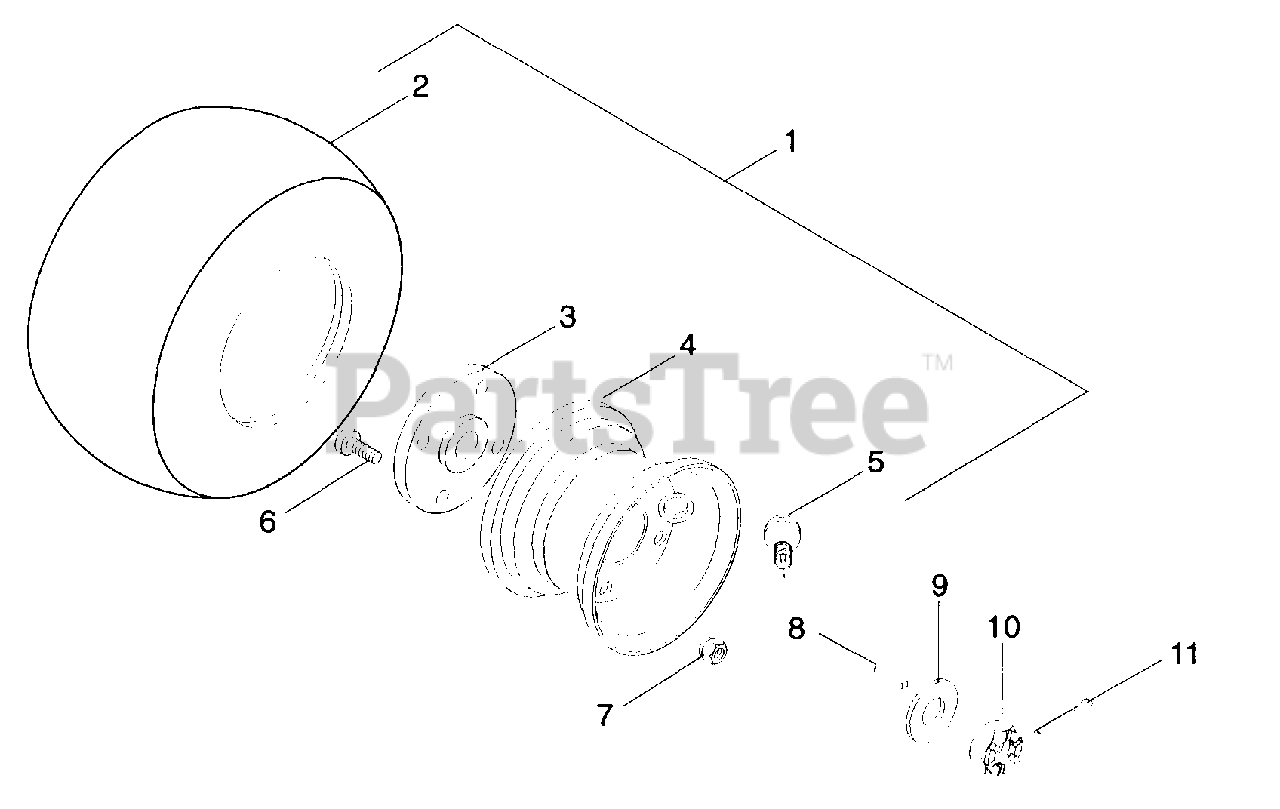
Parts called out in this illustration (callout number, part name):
1	Tire/Wheel Assembly, 16 x 6.50 - 8
2	Tire, 16 x 6.50 - 8
3	Assembly, Hub
4	Assembly, Rim
5	Valve Stem Assembly
6	Bolt, .50 - 20 x 1.25
7	Nut-Hex .50-20
8	Key, Square 3/16 x .750
9	Washer-Flat-Steel .781 x 1.500 x .060
10	Nut, Hex 3/4 - 28
11	Pin-Cotter .09 x 1.0
